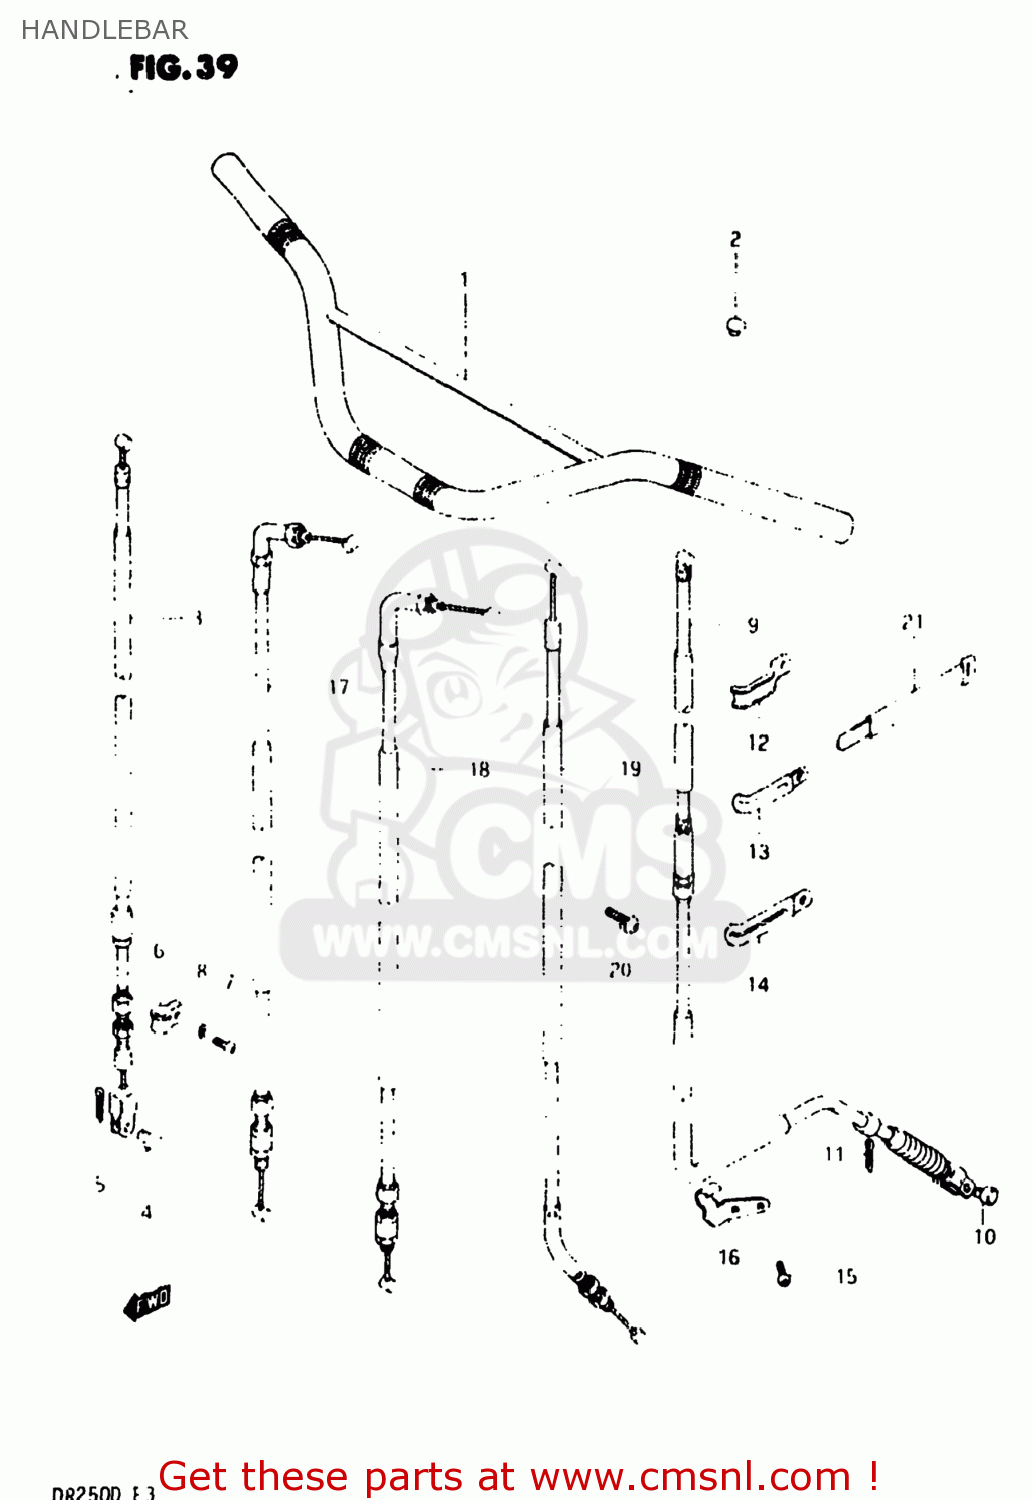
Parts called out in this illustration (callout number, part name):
1	HANDLEBAR
2	CAP(OD:14)
3	CABLE ASSEMBLY,FRONT BRAKE
4	PIN(L:17.5)
5	PIN
6	GUIDE,CABLE
7	SCREW
8	LOCK WASHER
9	CABLE ASSEMBLY,CLUTCH
10	PIN(L:13)
11	PIN
12	CLAMP
13	CLAMP
14	CLAMP
15	SCREW 6X12
16	STOPPER,CLUTCH CABLE
17	CABLE ASSY,THROTTLE NO.1
18	CABLE ASSY,THROTTLE NO.2
19	CABLE ASSEMBLY,DECOMPRESSION
20	SCREW
21	CLAMP(L:250)
